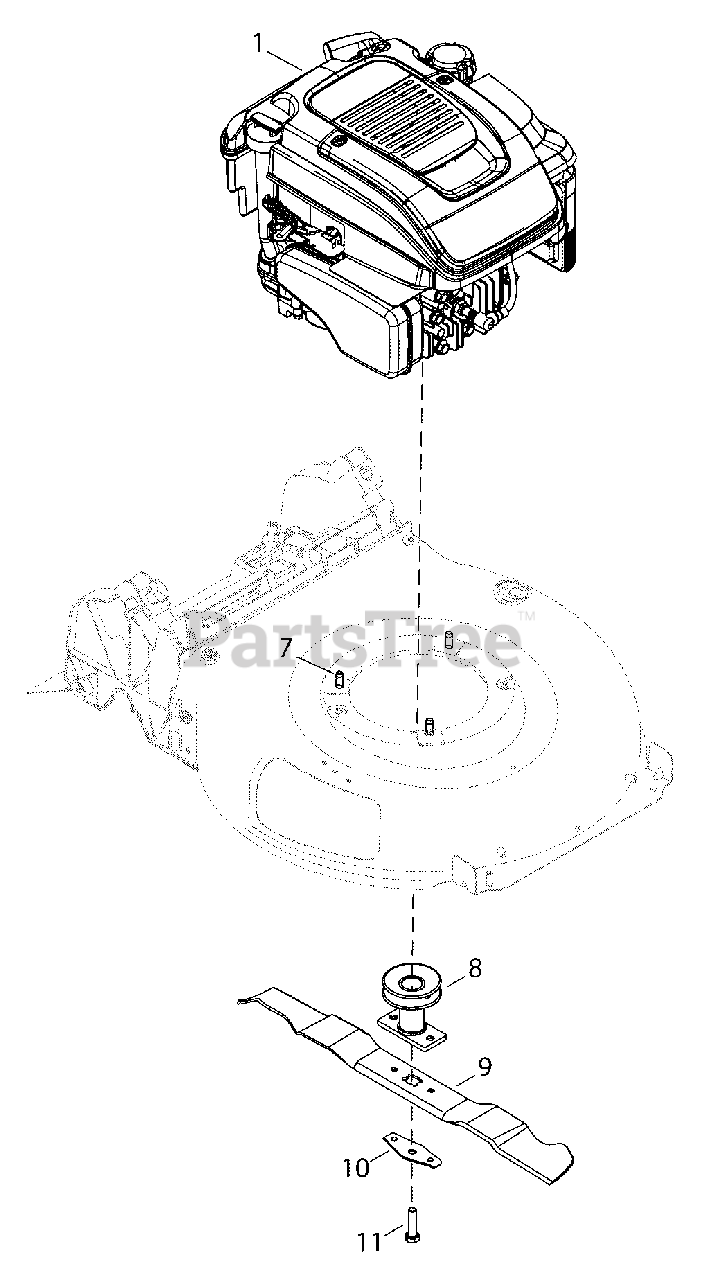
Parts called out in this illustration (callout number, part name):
1	* ENGINE, Briggs & Stratton, Mod. 111P02-0007-F1
7	SCREW, Engine Mounting, 3/8-16 x 1
8	ASSEMBLY, Blade Adapter
9	BLADE, Mulching
9	BLADE, High Lift
10	SUPPORT, Blade Bell
11	SCREW Hex, 3/8-24 x 1-1/2
